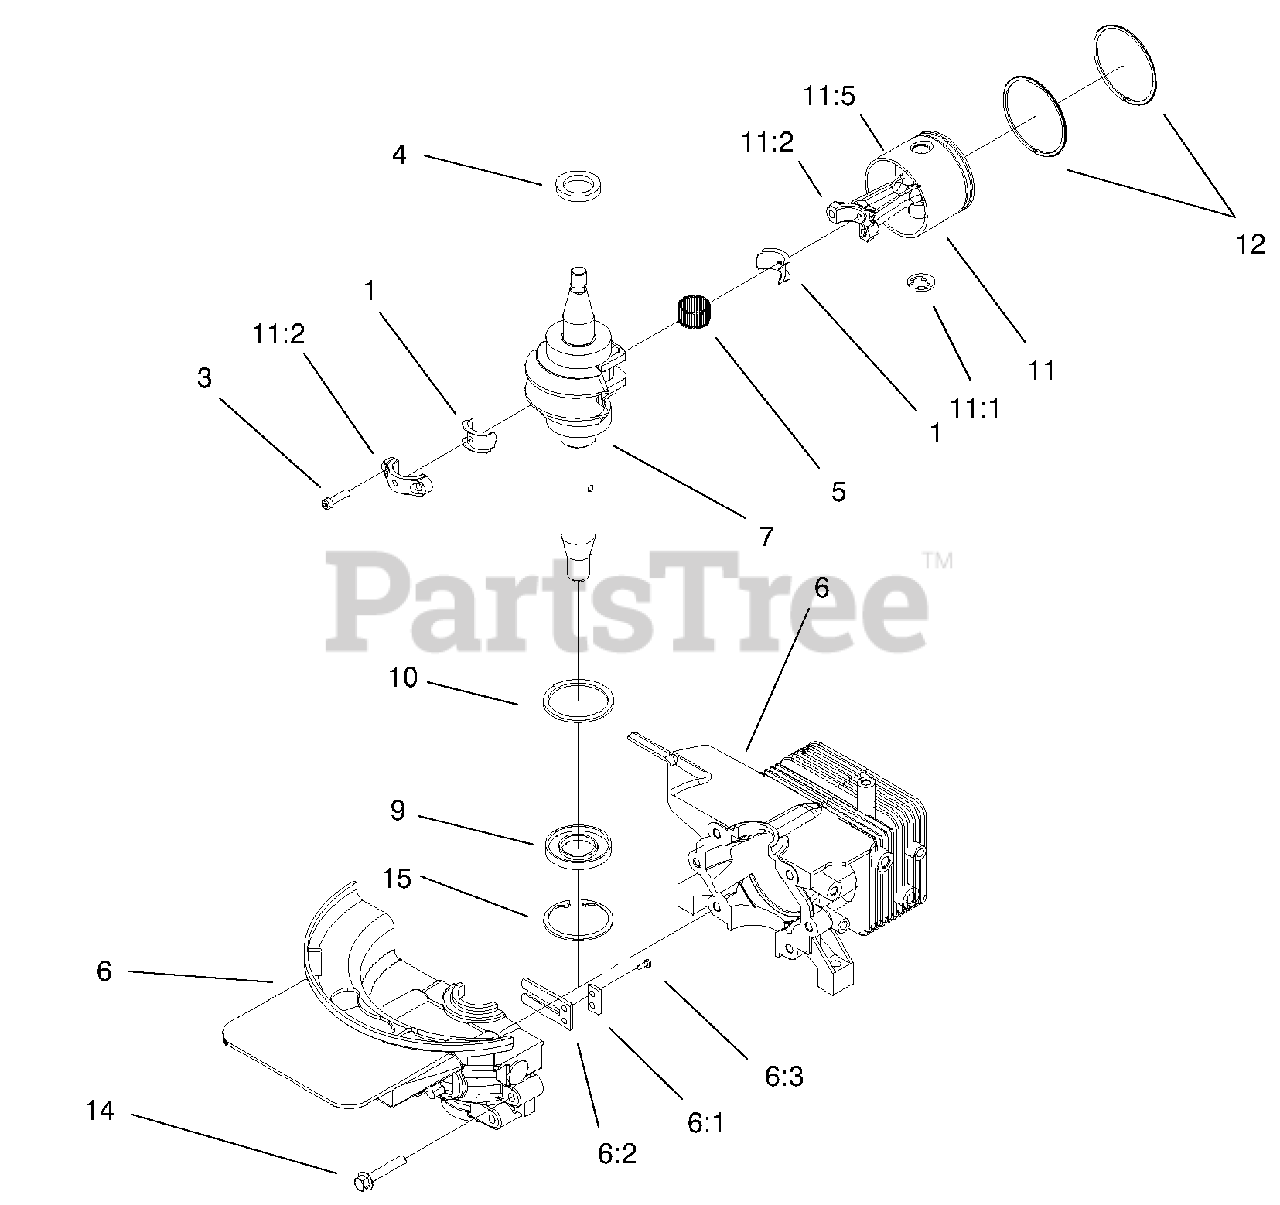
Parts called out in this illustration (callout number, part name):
1	LINER ASM
3	SCREW-HSH
4	SEAL-OIL
5	BEARING-NEEDLE
6	CYLINDER AND CRANKCASE ASM
6:1	PLATE-BACKUP, REED
6:2	REED-CARBURETOR
6:3	SCREW-HH
7	CRANKSHAFT AND BEARING ASM
9	SEAL-OIL
10	RING-RET. EX
11	Piston And Connecting Rod ASM
11:1	RING-RETAINING
11:2	CONNECTING ROD ASM
11:5	PISTON AND RINGS ASM
15	RING-RETAINING
